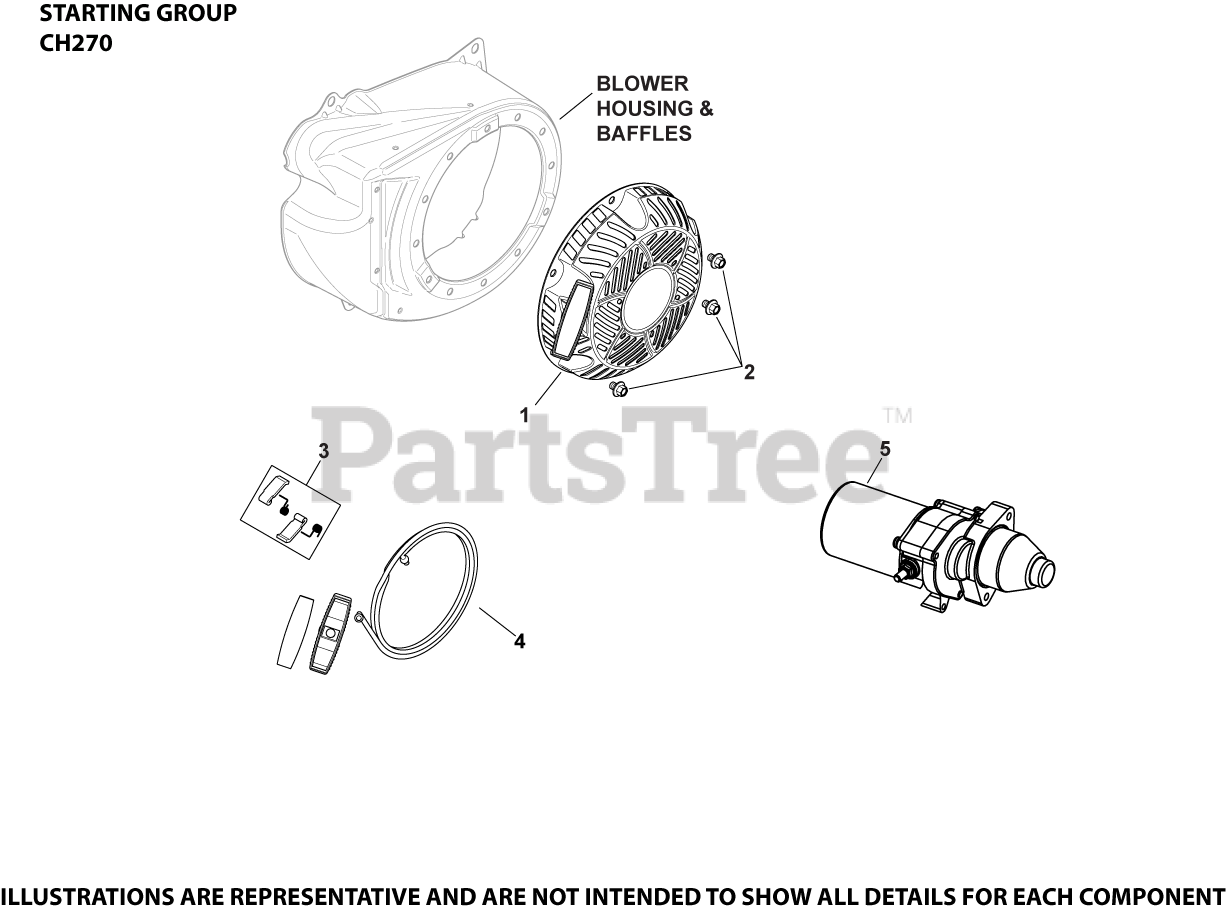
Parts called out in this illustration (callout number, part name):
1	RETRACTABLE STARTER ASSEMBLY
2	SCREW, M6 X 8 HEX FLANGE HEAD
3	KIT, PAWL REPAIR
4	ROPE, STARTING
